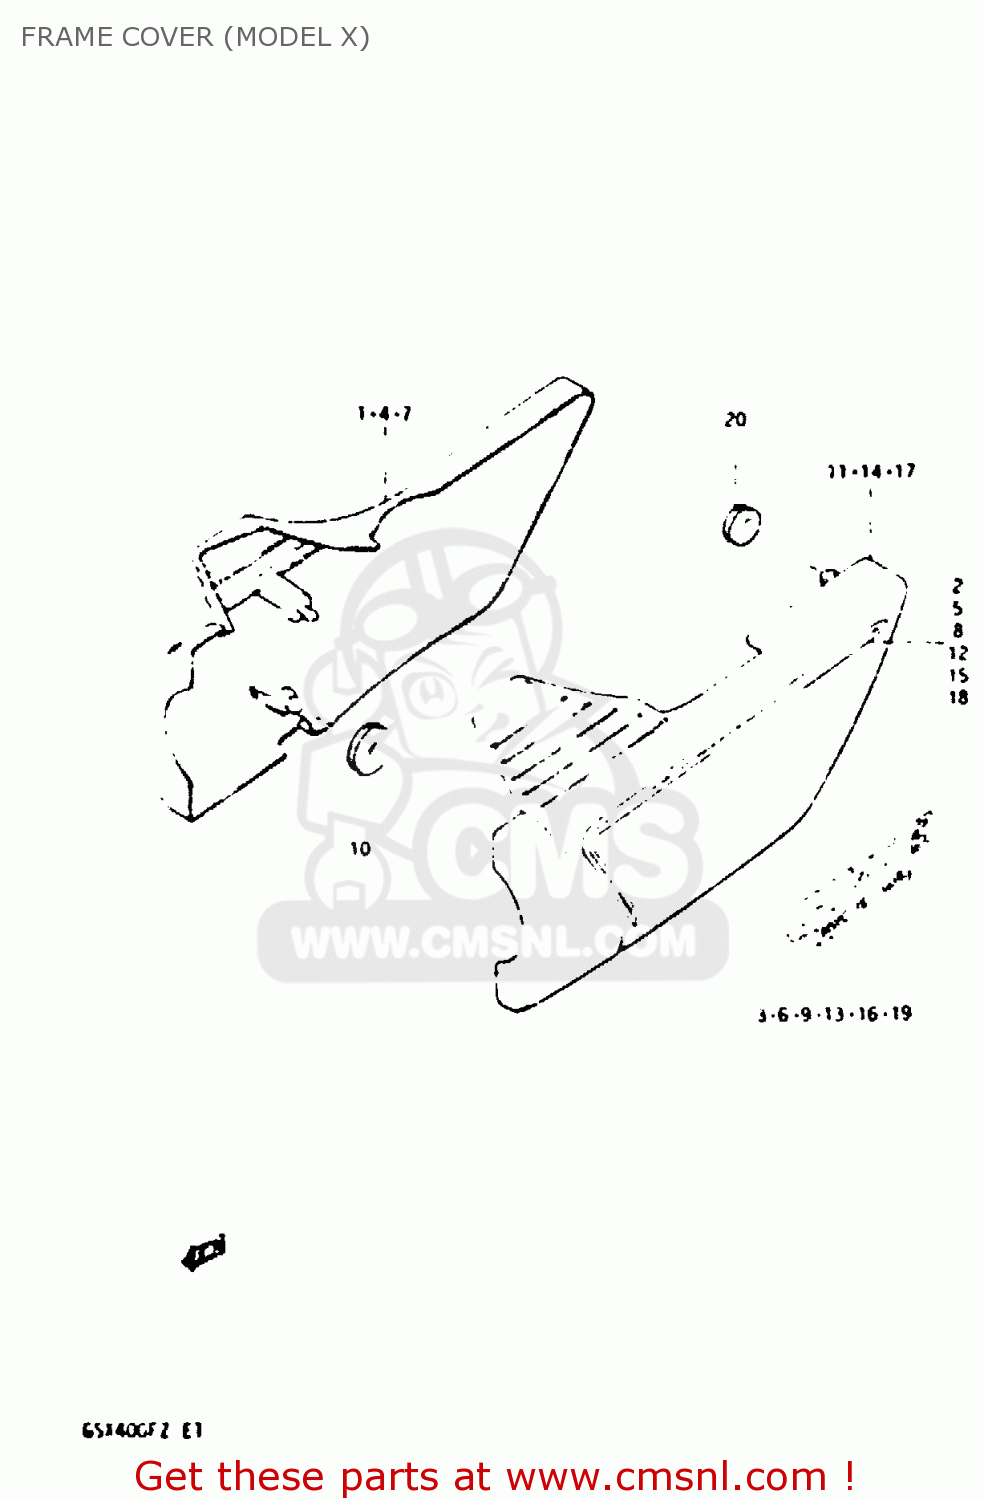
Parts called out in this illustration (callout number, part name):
1	COVER, FRAME RH (BLUE)
2	TAPE, RH
3	EMBLEM, LH
4	COVER,FRAME RH
5	TAPE, RH
6	EMBLEM, LH
7	COVER, FRAME RH (RED)
8	TAPE, RH
9	EMBLEM, LH
10	CUSHION
11	COVER, FRAME LH (BLUE)
12	TAPE, LH
13	EMBLEM, LH
14	COVER, FRAME LH
15	TAPE, LH
16	EMBLEM, LH
17	COVER,FRAME LH
18	TAPE, LH
19	EMBLEM, LH
20	CUSHION
